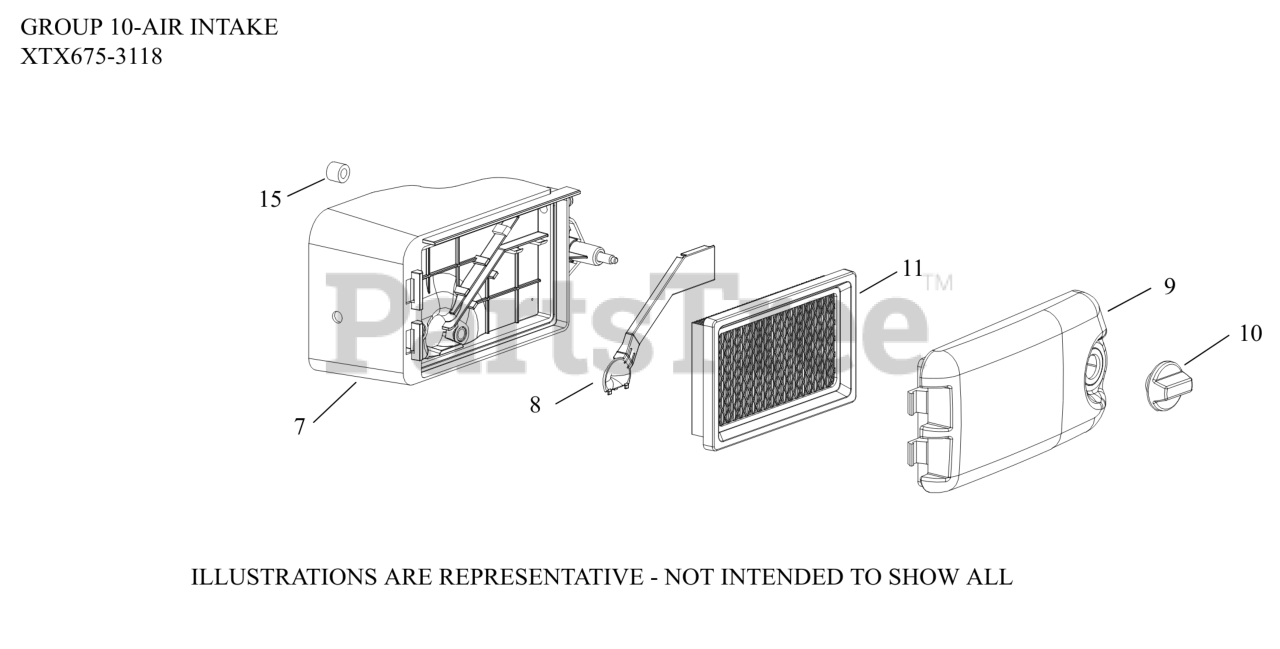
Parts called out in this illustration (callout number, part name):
7	AIR CLEANER BASE-USE 14 094 23-S
8	COVER, A/C BASE (BREATHER GAS)
9	COVER, AIR CLEANER
10	KNOB-USE 14 341 07-S
11	ELEMENT, AIR FILTER
15	SPACER, AIR CLEANER BASE
